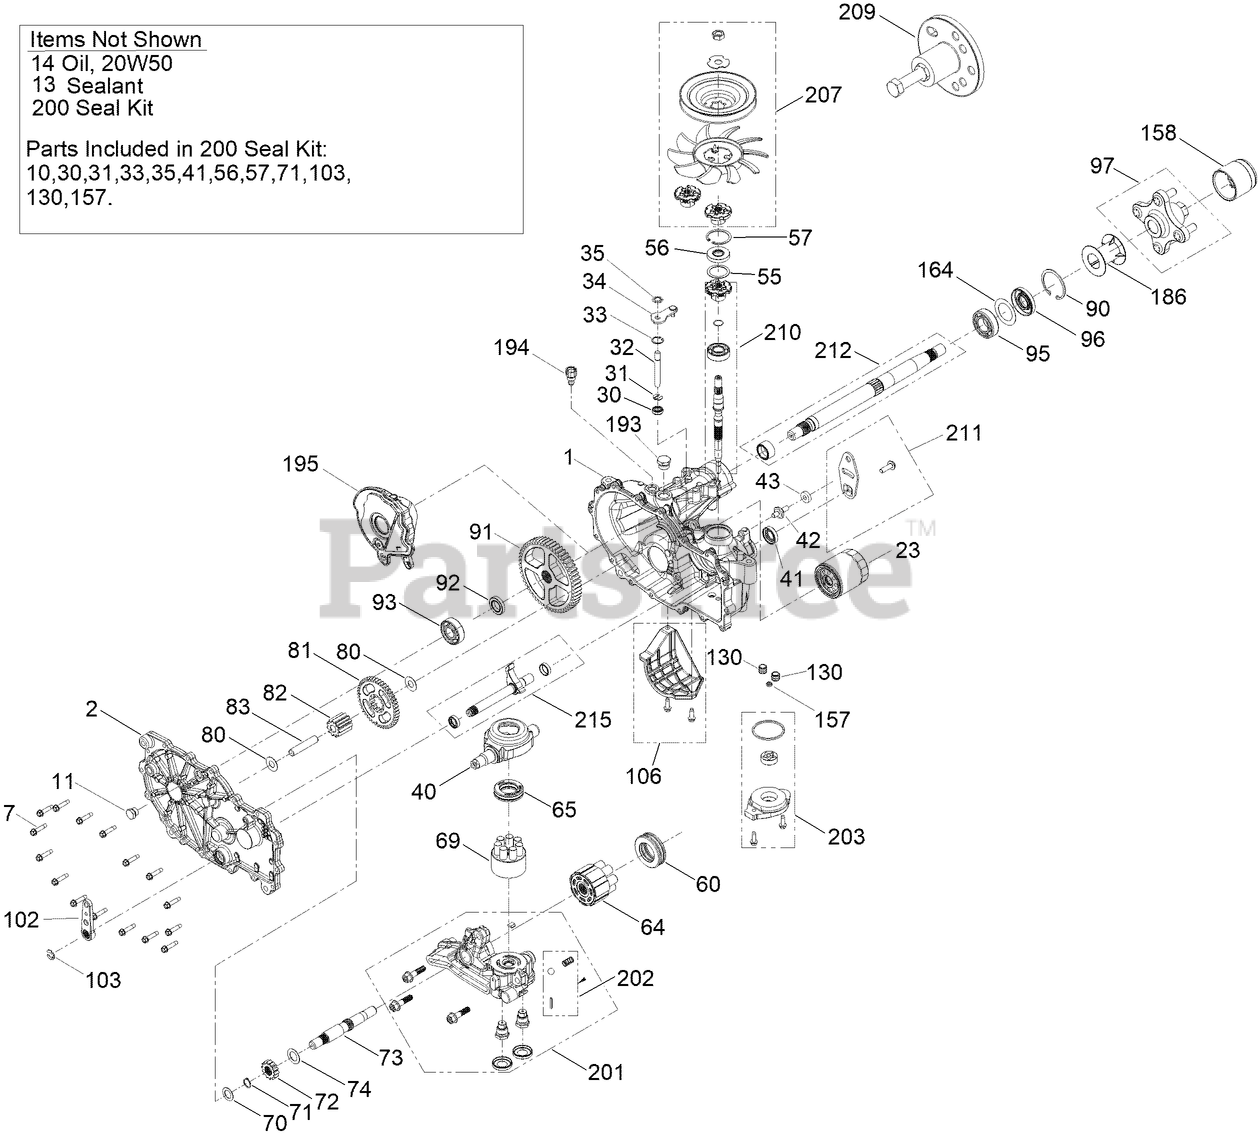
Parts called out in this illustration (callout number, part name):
1	LH MAIN HOUSING KIT
2	LH SIDE COVER KIT
7	SCREW-HHF
13	SEALANT
23	ELEMENT-OIL FILTER, HYD
30	SEAL-LIP
31	RING-RETAINING, EXTERNAL
32	ROD-BYPASS
33	RING-RETAINING, INTERNAL
34	ARM-BYPASS
35	RING-RETAINING, EXTERNAL
40	SWASHPLATE-TRUNNION
41	SEAL-LIP
43	PUCK-FRICTION
55	SPACER
57	RING-RETAINING
60	BEARING-THRUST
64	CYLINDER BLOCK ASM KIT
65	BEARING-THRUST
69	PUMP BLOCK ASM
70	WASHER-FLAT
71	RING-RETAINING
72	GEAR-14T
73	SHAFT-MOTOR
74	WASHER
80	WASHER
81	GEAR-45T
82	GEAR-11T
90	RING-RETAINING
91	GEAR-54T
92	SPACER
93	BEARING-BALL
95	BEARING-BALL
97	HUB-OFFSET
102	HANDLE-BRAKE
103	RING-RETAINING, EXT
106	FILTER GUARD KIT
130	TUBE-CHARGE
157	GEROTOR SEAL KIT
158	CAP-AXLE, LONG
164	SPACER
186	TUBE-AXLE
194	BREATHER FITTING ASM
195	LH INTERNAL EXPANSION TANK ASM
200	SEAL KIT
202	CHARGE RELIEF KIT
203	CHARGE KIT
207	FAN AND PULLEY KIT
210	INPUT SHAFT KIT
211	CONTROL ARM KIT
215	INBOARD KIT
